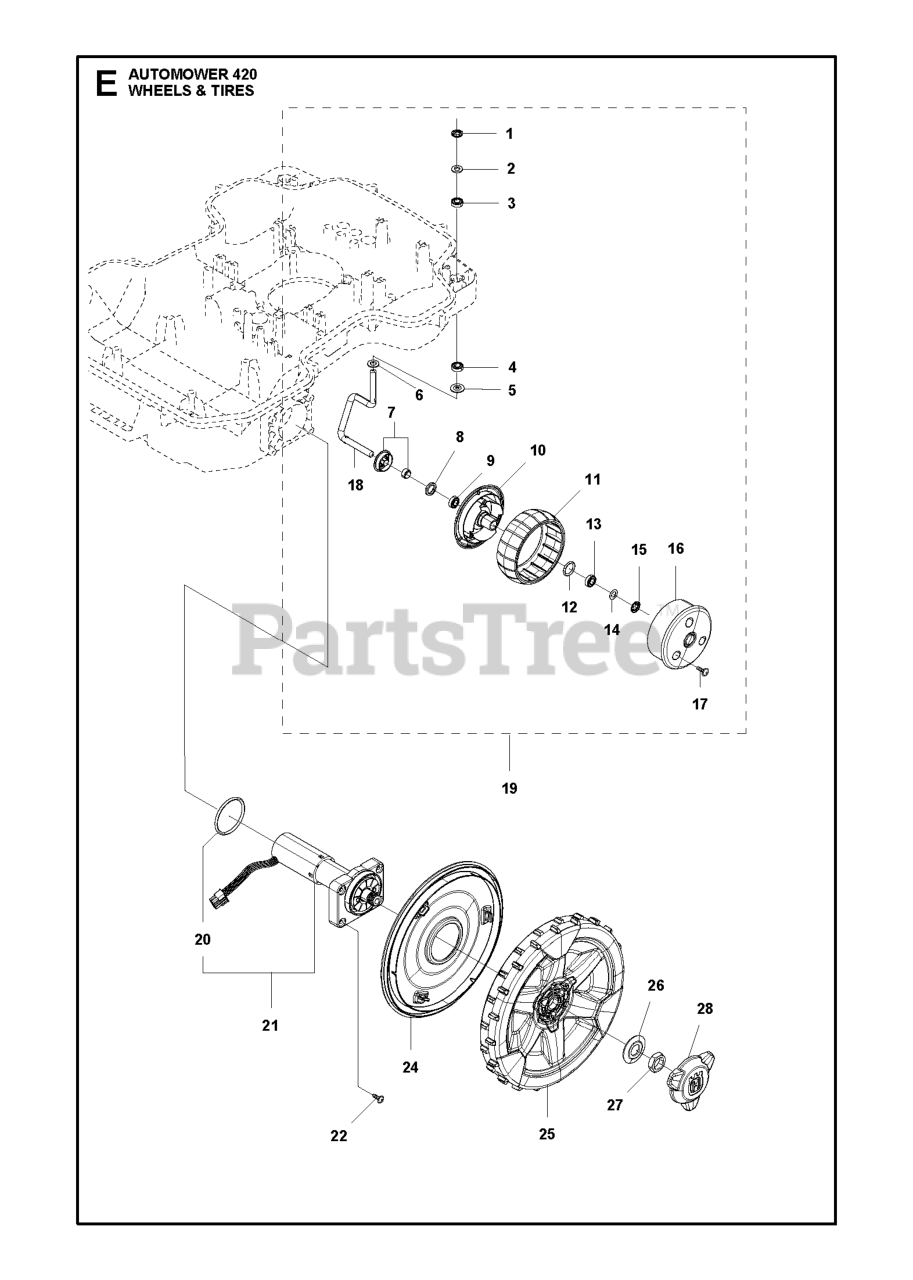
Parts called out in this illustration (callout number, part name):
1	SPRING.INTERLOCK
2	CAM.INTERLOCK.RELEASE
3	RP SPRING, TORSION
4	SPRING RETAINER
5	SCREW 14-20 X 5/8
6	STOP.INTERTLOCK.SPRING
